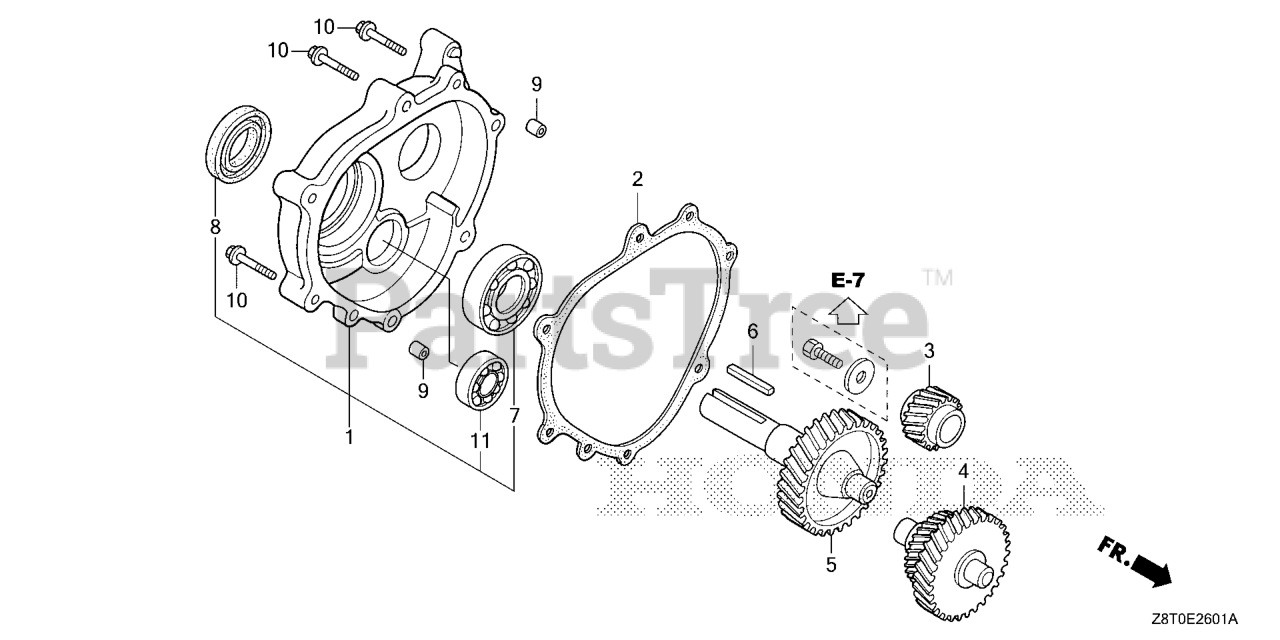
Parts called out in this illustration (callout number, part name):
1	COVER ASSY., GEAR CASE
2	GASKET, CHAIN CASE COVER
3	GEAR, PRIMARY DRIVE (12T)
4	COUNTERSHAFT (13T/27T)
5	SHAFT, P.T.O. (H-TYPE)
6	KEY (6.3X6.3X43)
7	BEARING, RADIAL BALL (6206) (NTN CORP.)
8	OIL SEAL (30X46X8) (NOK ASIA)
9	PIN A, DOWEL (8X14)
10	BOLT, FLANGE (8X40) Use up to Engine SN 1003236.
11	BEARING, RADIAL BALL (6302)
